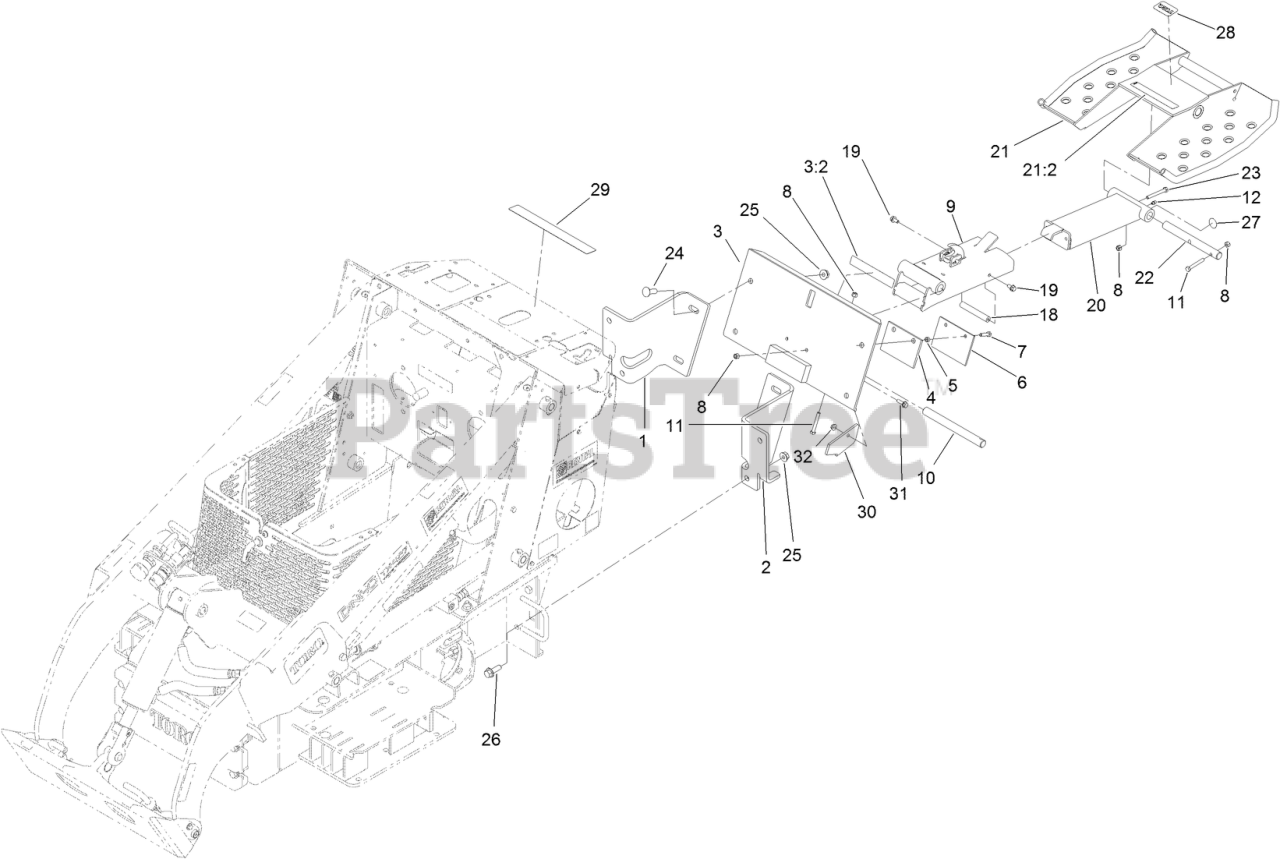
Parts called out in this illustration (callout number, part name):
1	PLATE-MTG, TX PLATFORM, RH
2	PLATE-MTG, TX PLATFORM-LH
3	SULKY MOUNTING PLATE ASM
3:2	DECAL-POINT, PINCH
4	PAD-RUBBER
5	SPACER
6	PLATE-PUSH
7	SCREW-HH
8	NUT-LOCK, NI
9	LINKAGE ASM
10	PIN-UPPER
11	SCREW-HSH
12	FITTING-GREASE
18	ROD-CLAMP
19	SCREW-HHF
20	SLIDE ASM, WELDED
21	PLATFORM ASM
21:2	DECAL-POINT, PINCH
22	PIN-LOWER V
23	SCREW-HH
24	SCREW-CARR
25	NUT-HHF
26	SCREW-HHF
27	DECAL-GREASE
28	DECAL
29	DECAL-WARNING/INSTRUCTIONAL
30	PLATE-BUMPER
31	SCREW-HHF
32	NUT-HF
